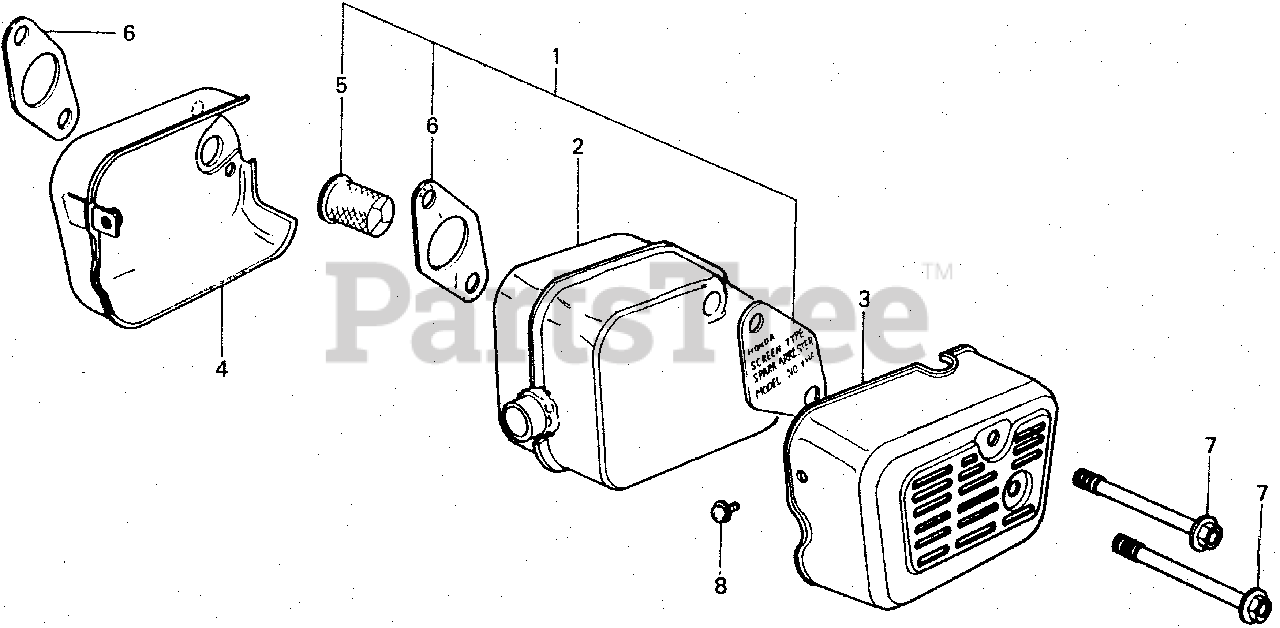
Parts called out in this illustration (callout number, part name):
1	ARRESTER KIT, SPARK
3	PROTECTOR, MUFFLER
4	SEPARATOR, MUFFLER (NOT AVAILABLE)
5	ARRESTER KIT, SPARK
6	GASKET, MUFFLER
7	BOLT, FLANGE (8X100)
8	SCREW-WASHER (5X10)
